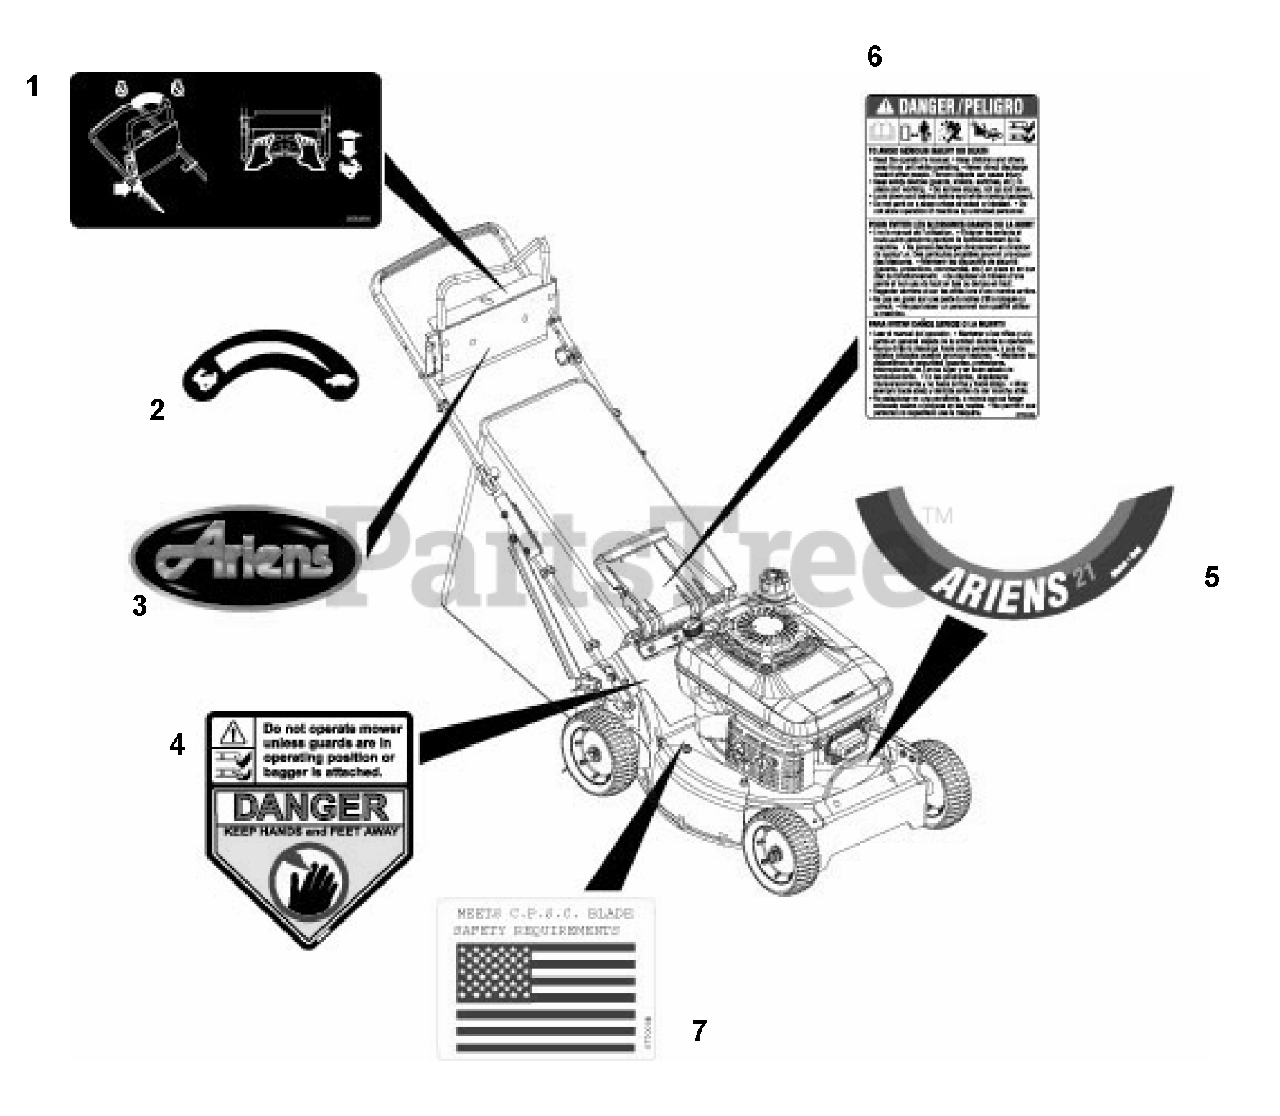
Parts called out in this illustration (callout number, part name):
1	DECAL,CONTROL
2	DECAL, TURTLE & RABBIT
3	DECAL-ARIENS JEWEL
4	DECAL, CPSC DANGER
5	DECAL, ARIENS DECK (PRO HONDA)
6	DECAL, BILINGUAL DANGER
7	DECAL, CPSC/USA FLAG
